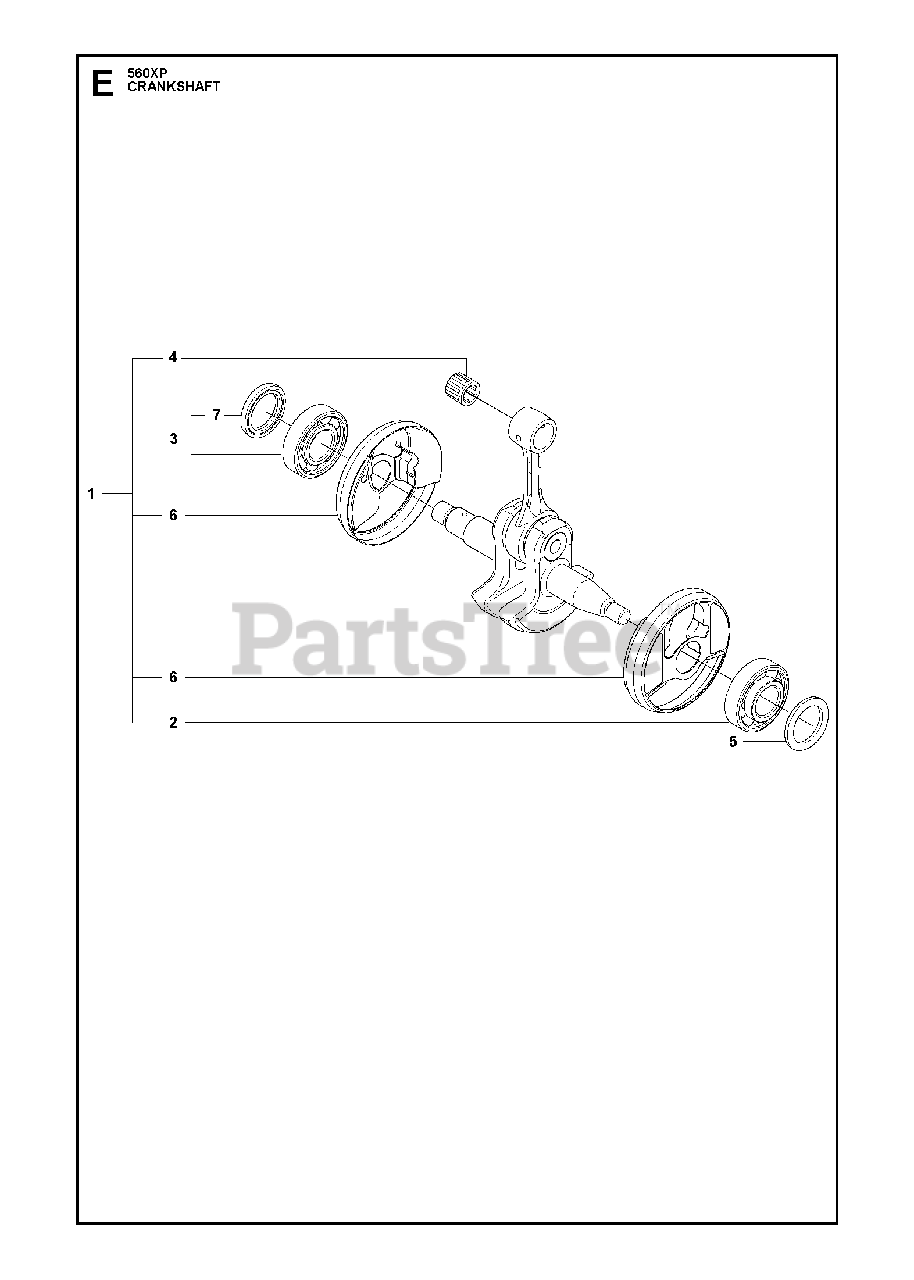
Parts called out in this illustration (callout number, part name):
2	BALL BEARING
3	BALL BEARING
4	NEEDLE BEARING
5	RADIAL SEAL
6	CUP
7	RADIAL SEAL
